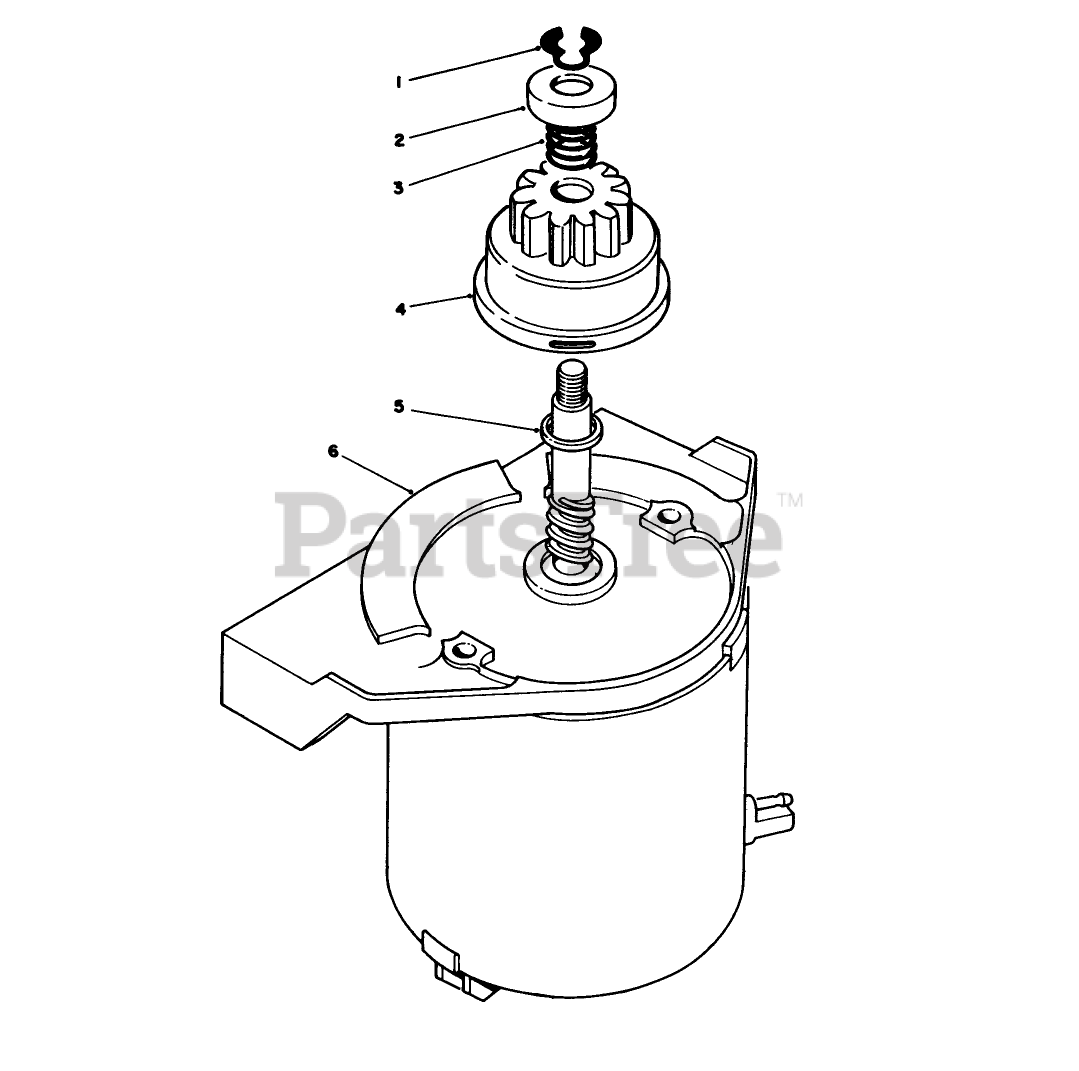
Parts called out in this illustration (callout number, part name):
1	RING-RETAINING
2	PINION STOP
3	COMPRESSION SPRING
4	PINION ASM
5	SPACER
6	END FRAME ASSY, MOTOR
